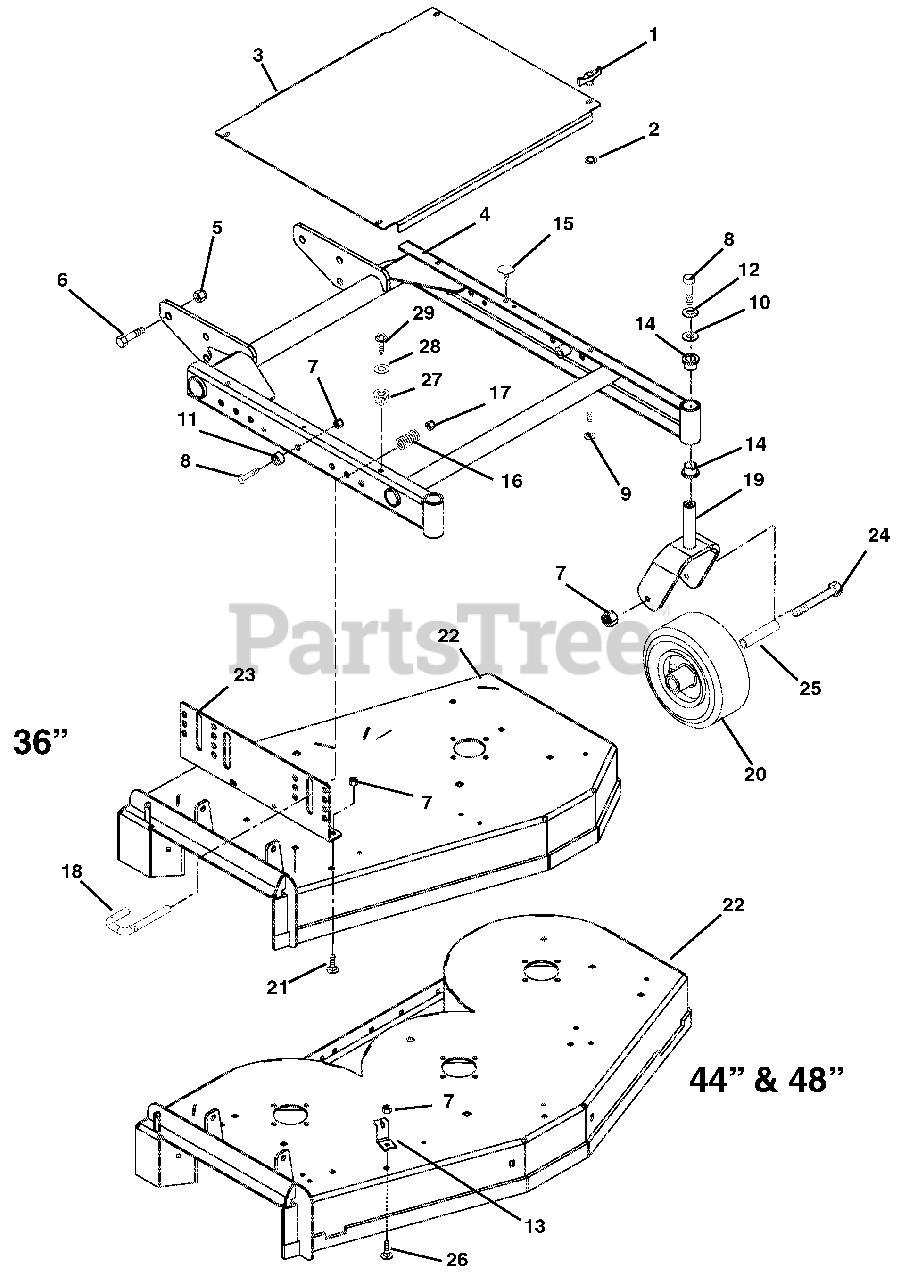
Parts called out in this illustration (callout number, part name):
1	Knob- Wing .312-18 (105, 106, 113)
2	Nut-Push .312 (105, 106, 113)
3	Cover, Belt Pro Mower(105, 312)
4	Weldment - Mower Frame 36"(105, 312)
5	Nut-Locking-Nylon .625-11
6	Bolt-Hex .62-11 x 1.50
7	Nut-Locking-Top-Flange .38-16(105, 312)
8	Bolt-Hex .38-16 x 1.25 Grade 5
9	Bolt-Round Head Square Neck .31-18 x 1.00 (105, 106, 113)
10	Washer-Flat-Steel .38 x 1.50 x .125
11	Bushing
12	Washer-Locking .38 x .094 Regular
13	Anchor, Spring (106, 113)
14	Bushing-Flange 1.00 x 1.25 x 1.50 x 1.50
15	Bumper Grommet .125 x .25 Dia.
16	Spring-Compression .058 x .65 x 2.13
17	Nut-Locking-Center .50-13
18	Pin- Latch
19	Weldment-Caster Fork
20	Wheel 9 x 3.50
21	Bolt-Round Head Square Neck .38-16 x 1.00 Grade 5
22	Kit, 36" Fixed Mower Deck with Decals(105, 312)
23	Kit-Mower Side Support Bracket-Right Hand and Left Hand
24	Bolt-Hex .38-16 x 5.50
25	Bearing .625 x .380 x 4.08
26	Bolt-Round Head Square Neck .38-16 x .75 Grade 5
27	Grommet,Plastic(312)
28	Washer-Flat-Steel .281 x .62 x .065(312)
29	Screw-Tapping .25-20 x .50 Hex Washer Head(312)
